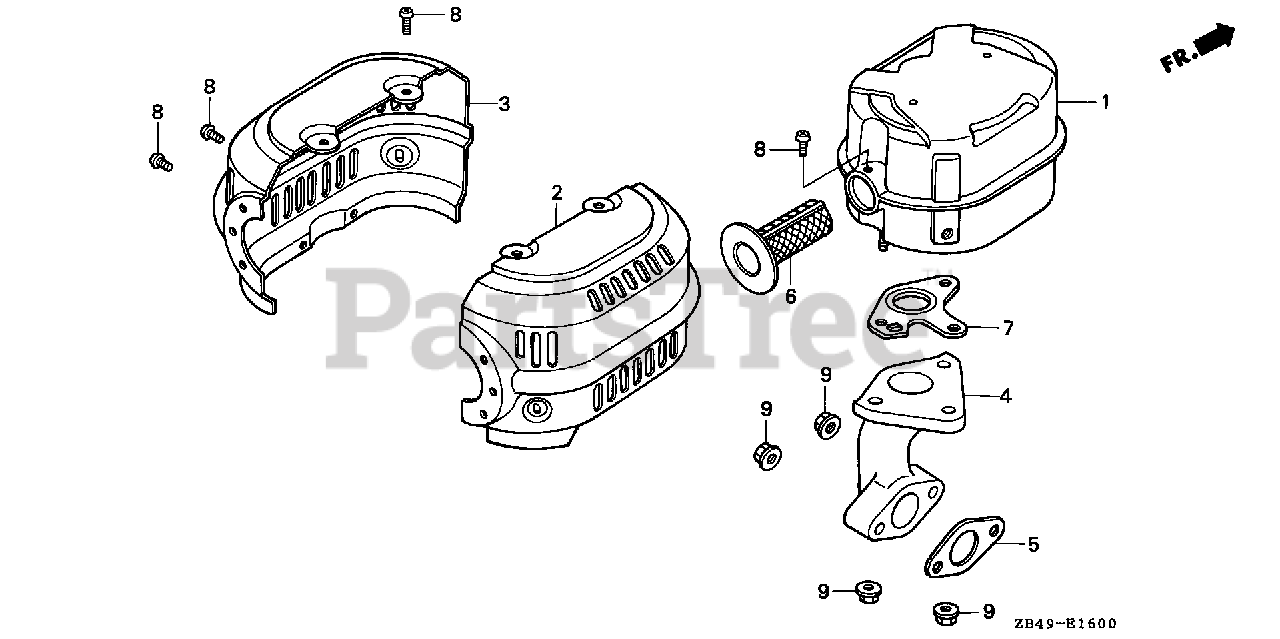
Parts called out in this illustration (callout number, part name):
1	MUFFLER (SILENT)
2	PROTECTOR, R. MUFFLER (SILENT)
3	PROTECTOR, L. MUFFLER (SILENT)
5	GASKET, EX. PIPE
6	ARRESTER, SPARK
7	GASKET, MUFFLER (ARRESTER) (NIPPON LEAKLESS)
8	SCREW, TAPPING (5X8)
9	NUT, FLANGE (8MM)
